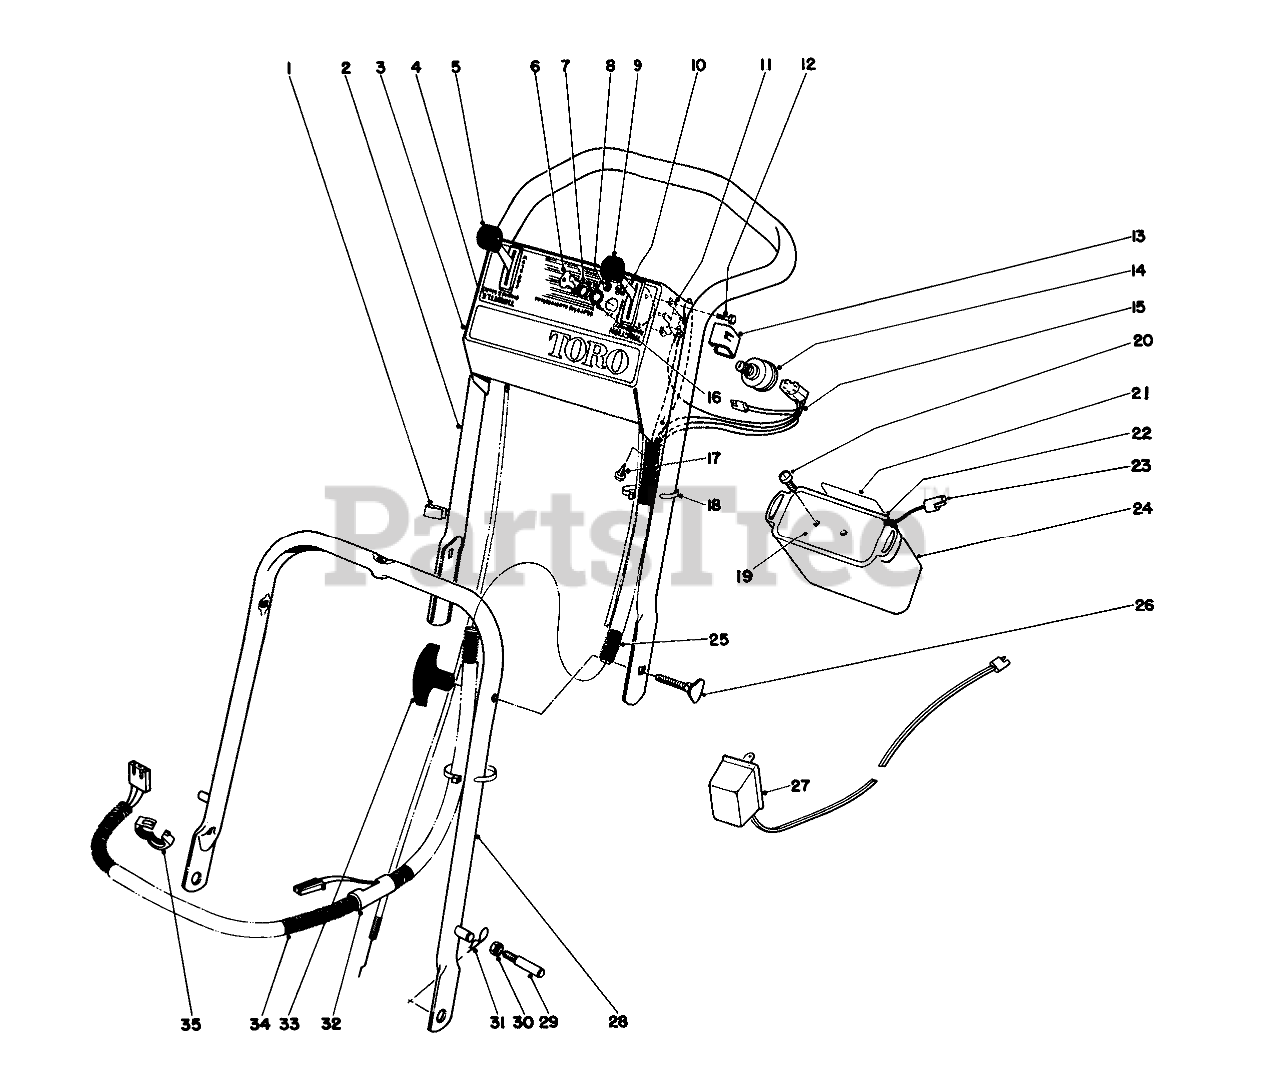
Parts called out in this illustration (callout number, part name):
2	UPPER HANDLE
3	Control Plate
4	Decal Control Plate
5	Control Throttle
8	NUT-HEX
9	Traction Control
10	WASHER-FLAT
11	CONTROL SWITCH
12	SCREW-HH
13	Cover Switch
14	SWITCH-STARTER
15	Wire Harness
16	WASHER-TOOTH, INTERNAL
17	SCREW-HWHTF
18	TIE-CABLE
19	BATTERY COVER
20	10-190X1/2 PAN HD SCR
21	Decal
22	Battery Assembly (Incl. Ref. #19-21 & 23-24)
23	Plug & Wire
24	Battery Case
25	Cover Wiring Harnes Upper
26	SCREW-HANDLE
27	Charger
28	Lower Handle
29	HANDLE PIN
30	Nut
31	PIN-COTTER, HAIR
32	Breakout Fitting
34	Cover Wiring Harness Lower
35	RING FITTING
